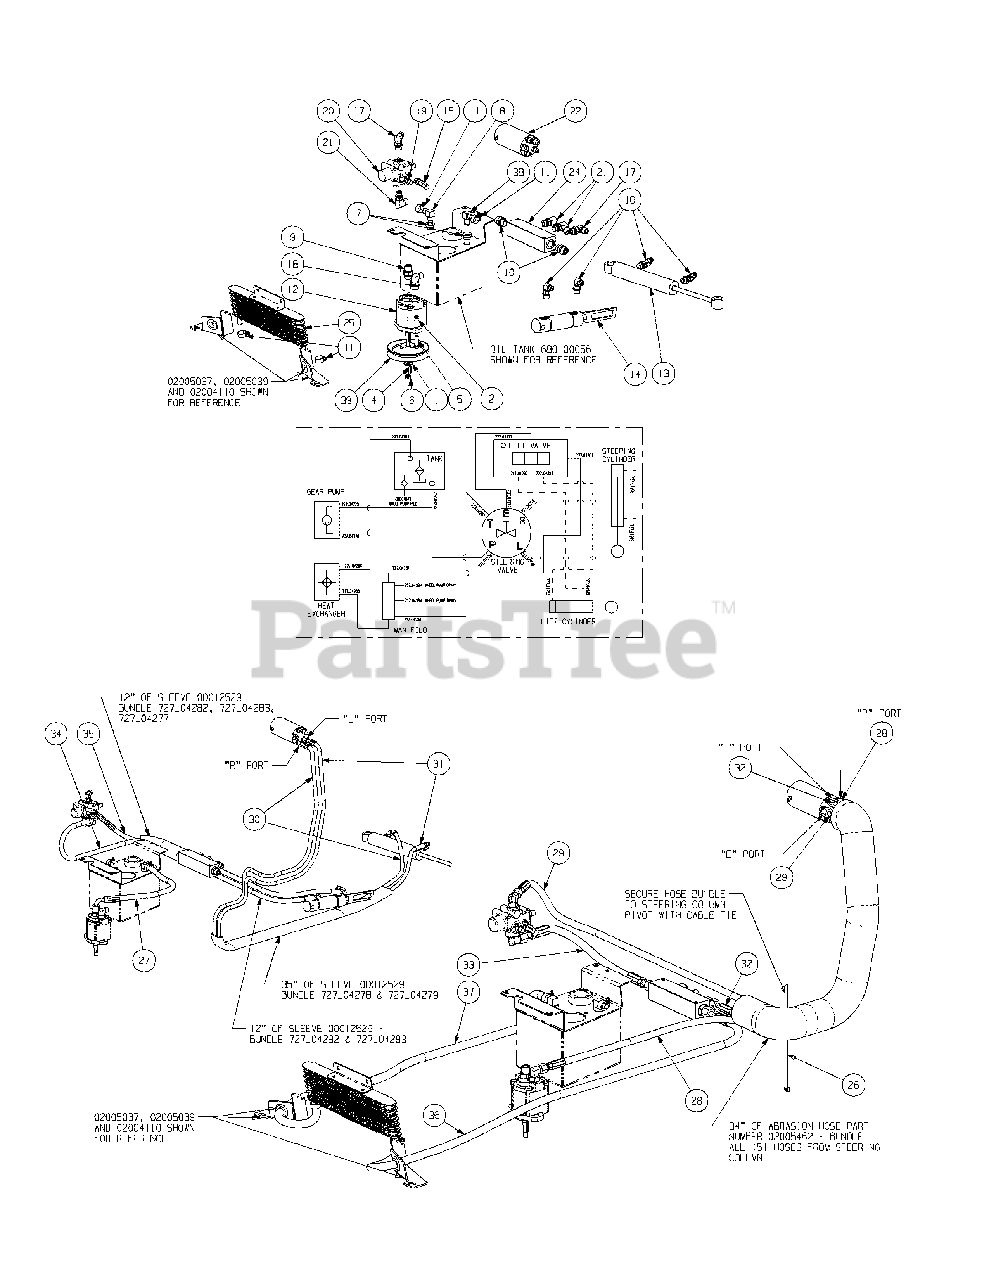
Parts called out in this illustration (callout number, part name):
1	Flat Washer, 3/8
2	Nut, 3/8-16, Nylock
3	Reel Return Line Sleeve, 1.59
4	Key, 3/16" x 7/8"
5	HHCS, 3/8-16 x 1.25
6	Hex Nut, 3/8-24
7	Grommet Fitting, .54 ID x .78 OD
8	Fitting Elbow Spur, 5/8 x 1/2
9	Adaptor Fitting, 8 x 10
10	Adaptor, 8 ORS x 8 ORB
11	Hose Clamp, 1/2
12	Pump, 3.5 Cu. Cm/Rev
13	Steering Cylinder
14	Hydraulic Cylinder, 1.50 x 2.75
15	Elbow Fitting, 40RB - 40RS, FS68001-04-04
16	Elbow Fitting, 40RB - 60RS, FS68001-04-06
17	Elbow Fitting, 60RB - 60RS, FS68001-06-06
18	Elbow Fitting, 60RS - 80RB, FS6801-06-08
19	Fitting, 40RB - 40RS, 4315 x 4
20	Hydraulic Lift Valve, Dual Action
21	Elbow Fitting, 80RS - 60RB, FS6801-08-06
22	Steering Valve
23	Anti Abrasion Sleeve
26	Cable Tie, 36.00 Long
27	Hose Assembly, Tank to Pump
28	Hose Assembly, Pump to Steering Valve
29	Hose Assembly, Steering Valve to Lift Valve
30	Hose Assembly, Steering Valve to Steering Extension
31	Hose Assembly, Steeering Valve to Steering Right Control
32	Hose Assembly, Steering Valve to Manifold
33	Hose Assembly, Lift Valve to Manifold
34	Hose Assembly, Lift Valve to Cylinder Right Control
35	Hose Assembly, Lift Valve to Cylinder Extension
36	Hose Assembly, Manifold to Exchanger
37	Hose Assembly, Exchanger to Tank
38	Elbow, 1/2 x 5/8 Barb w/ Straw
39	Hydro Pump Pulley
